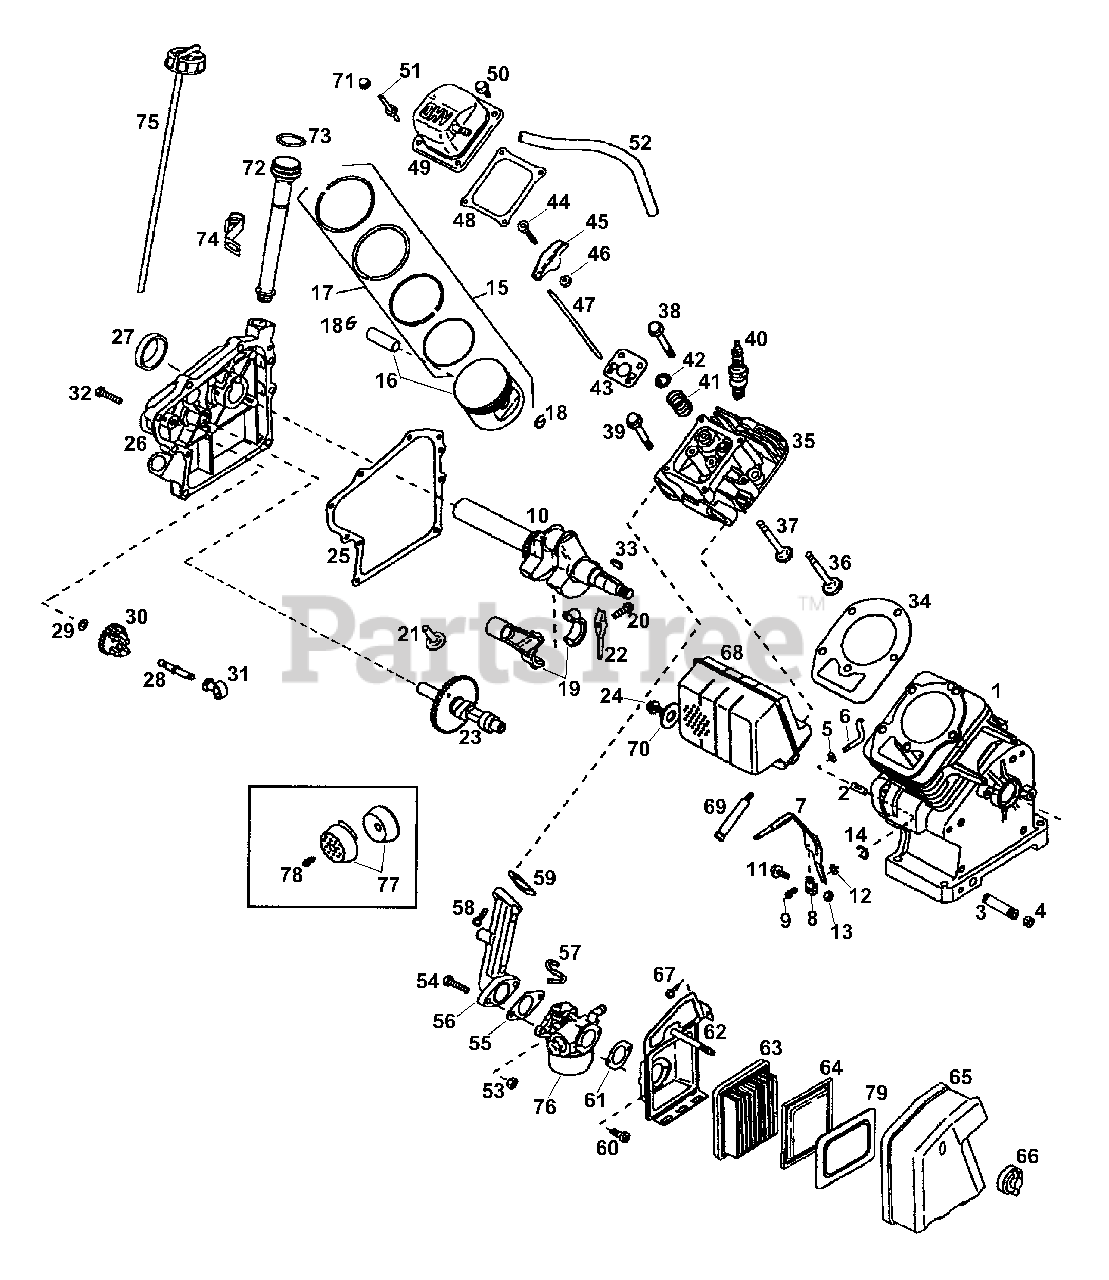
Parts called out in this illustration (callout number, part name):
1	Cylinder
2	Dowel Pin
3	Oil Drain Extension
4	Extension Cap
6	Governor Rod
7	Governor Lever
8	Governor Lever Clamp
9	Screw, Torx T-15, 8-32 x 3/8"
10	Crankshaft
11	Screw, 10-32 x 3/4"
12	Lock Washer
13	Lock Nut, 10-32
14	Retaining Ring
15	Piston, Pin & Ring Set (Standard)
16	Piston & Pin Assy (Standard)
17	Ring Set (Standard)
18	Piston Pin Retaining Ring
19	Connecting Rod Assy
20	Connecting Rod Bolt
21	Valve Lifter
22	Oil Dipper
24	Screw, 1/4-20 x 1-1/8"
25	Cylinder Cover Gasket
26	Cylinder Cover
28	Governor Shaft
30	Governor Gear Assy
31	Governor Spool
32	Screw, 1/4-20 x 1-1/4"
33	Flywheel Key
34	Cylinder Head Gasket
35	Cylinder Head
36	Exhaust Valve (Standard)
37	Intake Valve (Standard)
38	Screw, 5/16-18 x 1-1/2"
39	Screw, 5/16-18 x 2-41/64"
40	Resistor Spark Plug (N4C)
41	Valve Spring
42	Valve Spring Cap
43	Push Rod Guide
44	Rocker Arm Stud
45	Rocker Arm
46	Nut, 1/4-28
48	Rocker Arm Cover Gasket
49	Rocker Arm Cover
50	Screw, 1/4-20 x 31/64"
52	Breather Tube
53	Nut, 1/4-20
54	Screw, 1/4-20 x 1"
55	Carb. to Intake Pipe Gasket
56	Intake Pipe
57	Throttle Link
58	Screw, 1/4-20 x 1"
59	Intake Pipe Gasket
60	Screw, 10-32 x 1/2"
61	Air Cleaner Gasket
62	Air Cleaner Body
63	Air Cleaner Filter
64	Air Cleaner Filter (Poly)
65	Air Cleaner Cover
67	Screw, 10-32 x 31/64"
69	Screw, 1/4-20 x 2-9/32"
71	Nut & Lock Washer
72	Oil Fill Tube
74	Fill Tube Clip
75	Dipstick
76	Carburetor Assy
77	Spark Arrestor Kit
78	Screw, 8-32 x 3/8"
79	Air Cleaner Baffle
